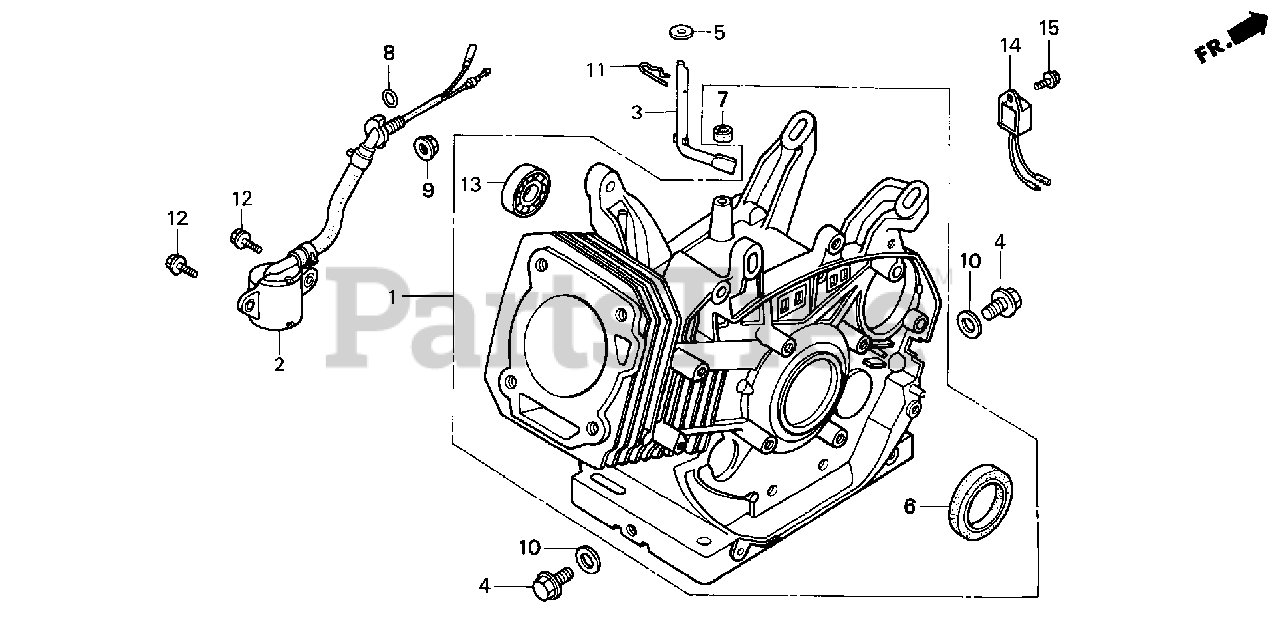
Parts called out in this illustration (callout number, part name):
1	CYLINDER ASSY. (SELF STARTER+ALERT)
2	SWITCH ASSY., OIL LEVEL
3	SHAFT, GOVERNOR ARM
4	BOLT, DRAIN PLUG
5	WASHER (8.2X17X0.8)
6	OIL SEAL (35X52X8)
7	OIL SEAL (8X14X5)
8	O-RING (14MM) (ARAI)
9	NUT, FLANGE (10MM)
10	WASHER, DRAIN PLUG (12MM)
11	PIN, LOCK (10MM)
12	BOLT, FLANGE (6X12)
13	BEARING, RADIAL BALL (6202)
14	ALERT UNIT, OIL
15	BOLT, FLANGE (6X12) (CT200)
